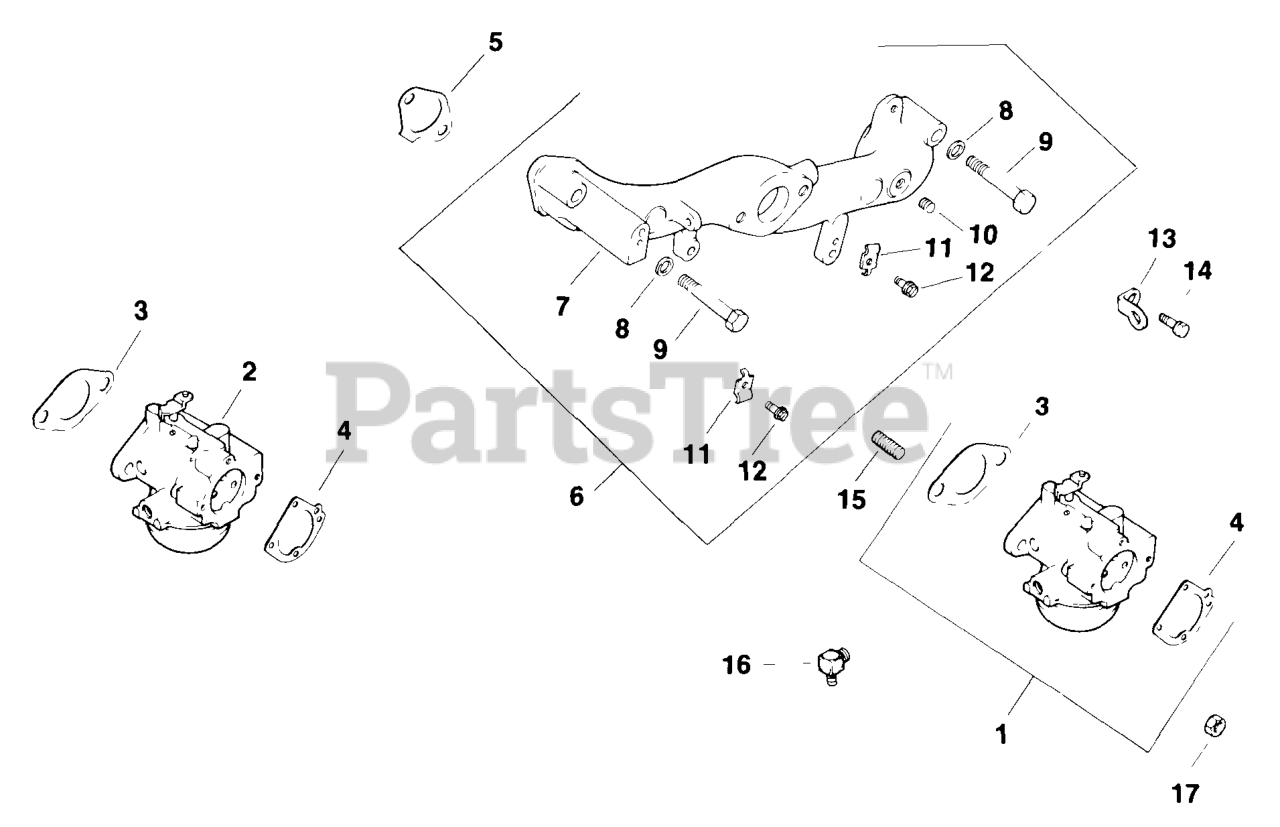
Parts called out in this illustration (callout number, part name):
1	Kit, Carburetor Adjustable Jet W/Gasket
3	Gasket, Carburetor
4	Gasket, Elbow
5	Gasket, Manifold
6	Kit, Intake Manifold
7	Manifold, Intake
8	Washer, Plain 5/16"
9	Screw, H.C. 5/16-18x2"
10	Plug, Hex. Ctsk. 1/8" N.P.T.F.
11	Clamp, Cable
12	Screw, Hex. Wash. Hd. 10-24x3/8"
13	Strap, Lifting
14	Screw, Hex. Wash. Hd. 1/4-20x3/4"
15	Stud 5/16-18x1"
16	Connector 90 Degree Hose
17	Nut, Hex. Jam 5/16-18
